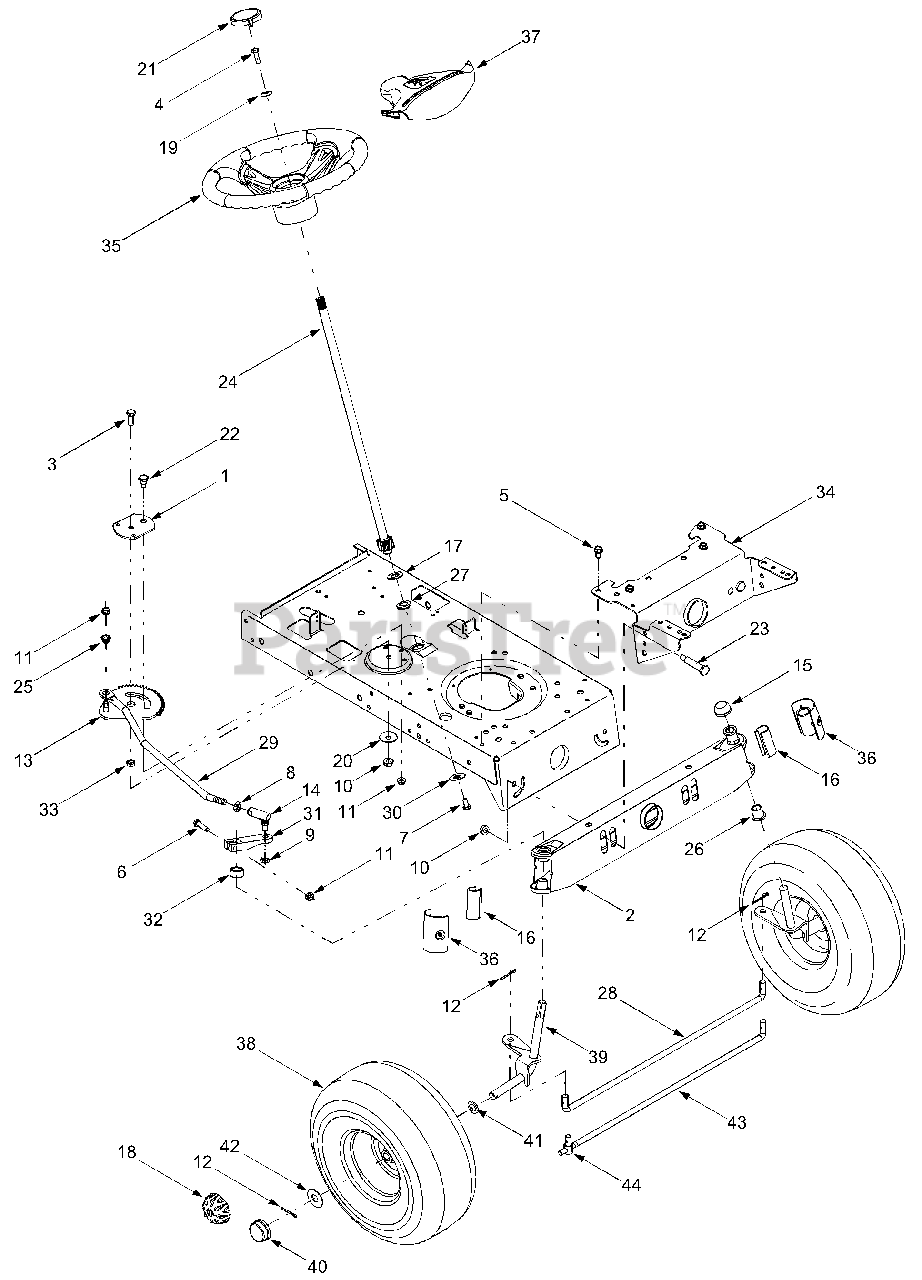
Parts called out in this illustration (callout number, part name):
1	Retainer Gear Segment Plate
4	Hex Cap Screw, 5/16-18 x 1.0
5	Self-tapping Screw, 5/16-12 x .75
6	Hex Cap Screw, 5/16-18 x 1.5
7	Machine Screw, 5/16-18 x .75
8	Jam Nut, 7/16-20 (Grade 2)
9	Jam Nut, 3/8-24
10	Flange Lock Nut, 3/8-16
11	Flange Lock Nut, 5/16-18
12	Cotter Pin, 1/8 x 1.25
13	Stearing Segment Gear
14	Ball Joint, 7/16 -20
15	Push Cap, .625
16	Axle End Cap, Standard
17	Flat Washer, .64 x 1.24 x .060
18	Deluxe Hub Cap
19	Bell Washer, .34 x .872 x .060
20	Bell Washer, .391 x .380 x .062
21	Steering Wheel Cap, Small
22	Shoulder Screw, .435 x .350, 5/16-18
23	Shoulder Screw, .498 x 2.045
24	Steering Shaft, 21.86
25	Plastic Bushing, .38 ID
26	Flange Bushing, .632 ID
27	Hex Flange Bearing, 5/8
28	Tie Rod, Non-adjustable
29	Steering Drag Link, 7/16-20
30	Cap, 1.25 x .16
31	Steering Arm
32	Spacer, 1.0 x .645 x .56
33	Spacer, .380 x .625 x .21
36	Axle End Cap, w/ Fitting
37	Steering Wheel Cap, Large
41	Flat Washer, .64 x 1.0 x .12
42	Flat Washer, .635 x 1.589 x .06
43	Tie Rod, Adjustable
44	Ferrule, 3/8-24 x .437 Dia
